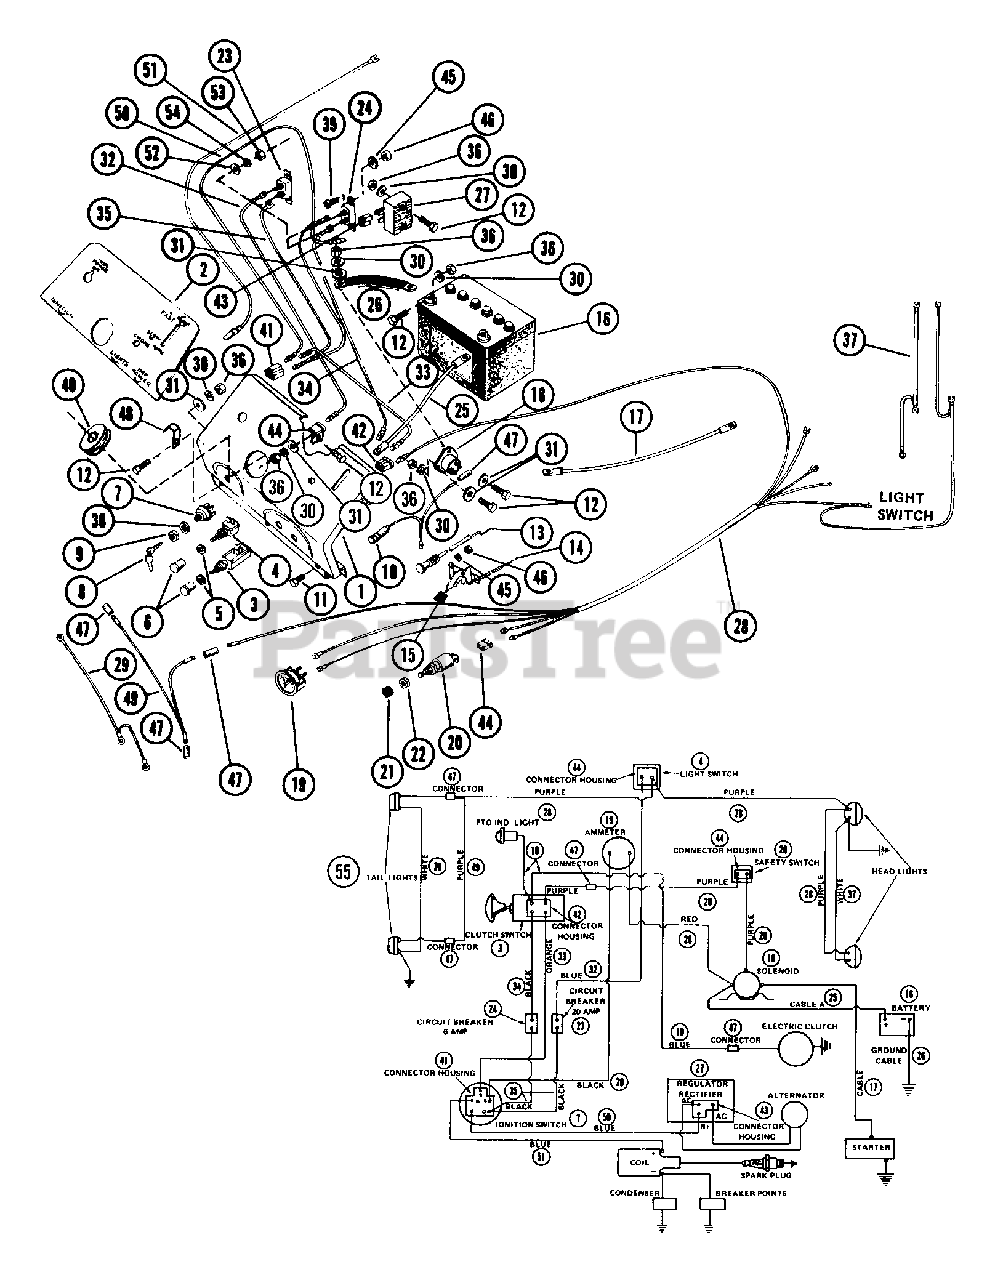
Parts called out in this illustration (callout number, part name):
1	DASH ASSEMBLY
2	DECAL-DASH S-12,S-14,S-16
3	CLUTCH SWITCH
4	LIGHT SWITCH
5	NUT .50-20 PL
7	IGNITION SWITCH
8	KEYS
9	NUT .562-24
10	P.T.O. INDICATOR & WIRE
11	SCR-TAP 10-16X.50 HWH PL AB
12	BLT-HEX .25-20X.75 PL GR2
13	CHOKE CONTROL
14	THROTTLE CONTROL
16	BATTERY
17	GROUND CABLE .31X22.00X.31
18	SOLENOID,STARTER SWITCH
19	AMMETER
20	SAFETY SWITCH
22	NUT-HEX .625-32 PL
23	CIRCUIT BREAKER
24	CIRCUIT BREAKER
26	GROUND CABLE
27	REGULATOR RECTIFIER
28	WIRE HARNESS
29	WIRE
30	WSHR-LK .250X.077 HVY PL
31	WSHR-FL-STL.281X.62X.065 PL
32	WIRE
33	WIRE
34	WIRE
35	WIRE
36	NUT-HEX .250-20 PL
37	WIRE
38	WSHR-LK-INT .563X.040 PL
39	SCR-MCH 10-24X.50 SLTR PL
40	GROMMET
41	CONNECTOR HOUSING
42	CONNECTOR
43	CONNECTOR
44	CONNECTOR
45	WSHR-LK 10X.047 MED PL
46	NUT-HEX 10-24 PL
47	WIRE CONNECTOR
49	WIRE
50	WIRE
51	WIRE
52	WSHR-FL-STL .219X.500X.049 PL
53	NUT 10-32 PL
54	WSHR-LK 10X.047 MED PL
55	TAIL LIGHT
